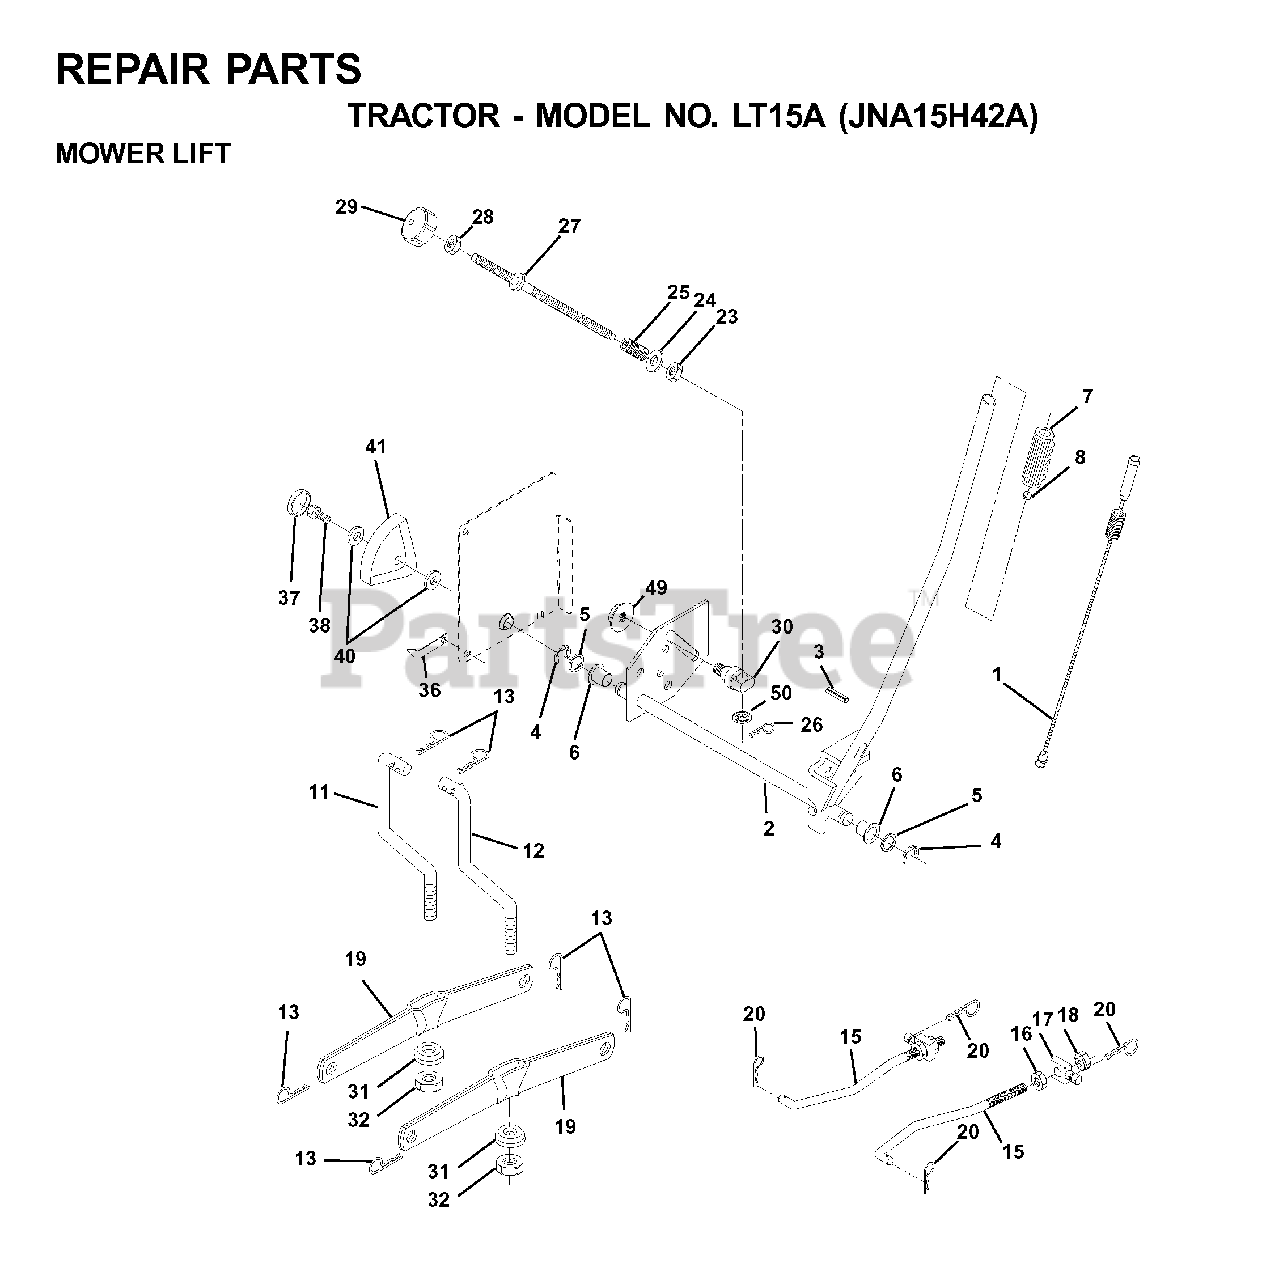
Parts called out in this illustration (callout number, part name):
1	WIRE ASM INNER W/ PLUNGER LT
2	SHAFT ASM R HANDLE
3	PIN GROOVE
4	RETAINING RING LT
6	BEARING.NYLON
7	GRIP HANDLE
8	PLUNGER BUT KIT
11	LINK LIFT LH
12	LINK LIFT RH
13	RETAINER-SPRNG RB
15	LINK.SUSPENSION.FRONT
16	NUT
17	TRUNION
18	NUT
19	ARM.REAR.SUSPENSION
20	SPRING RETAINER
25	SPRING**
26	RETAINER CLIP
27	ROD ADJ LIFT
28	NUT
29	KNOB INF 3/8-16
31	BEARING.PIVOT.LIFT
32	NUT CROWNLOCK 3/8-24
36	POINTER, HEIGHT INDICATOR
37	PLUG,HOLE
38	SCREW 5/16-18X1
41	IND. HEIGHT STLT
49	NUT
50	NUT PUSH M
